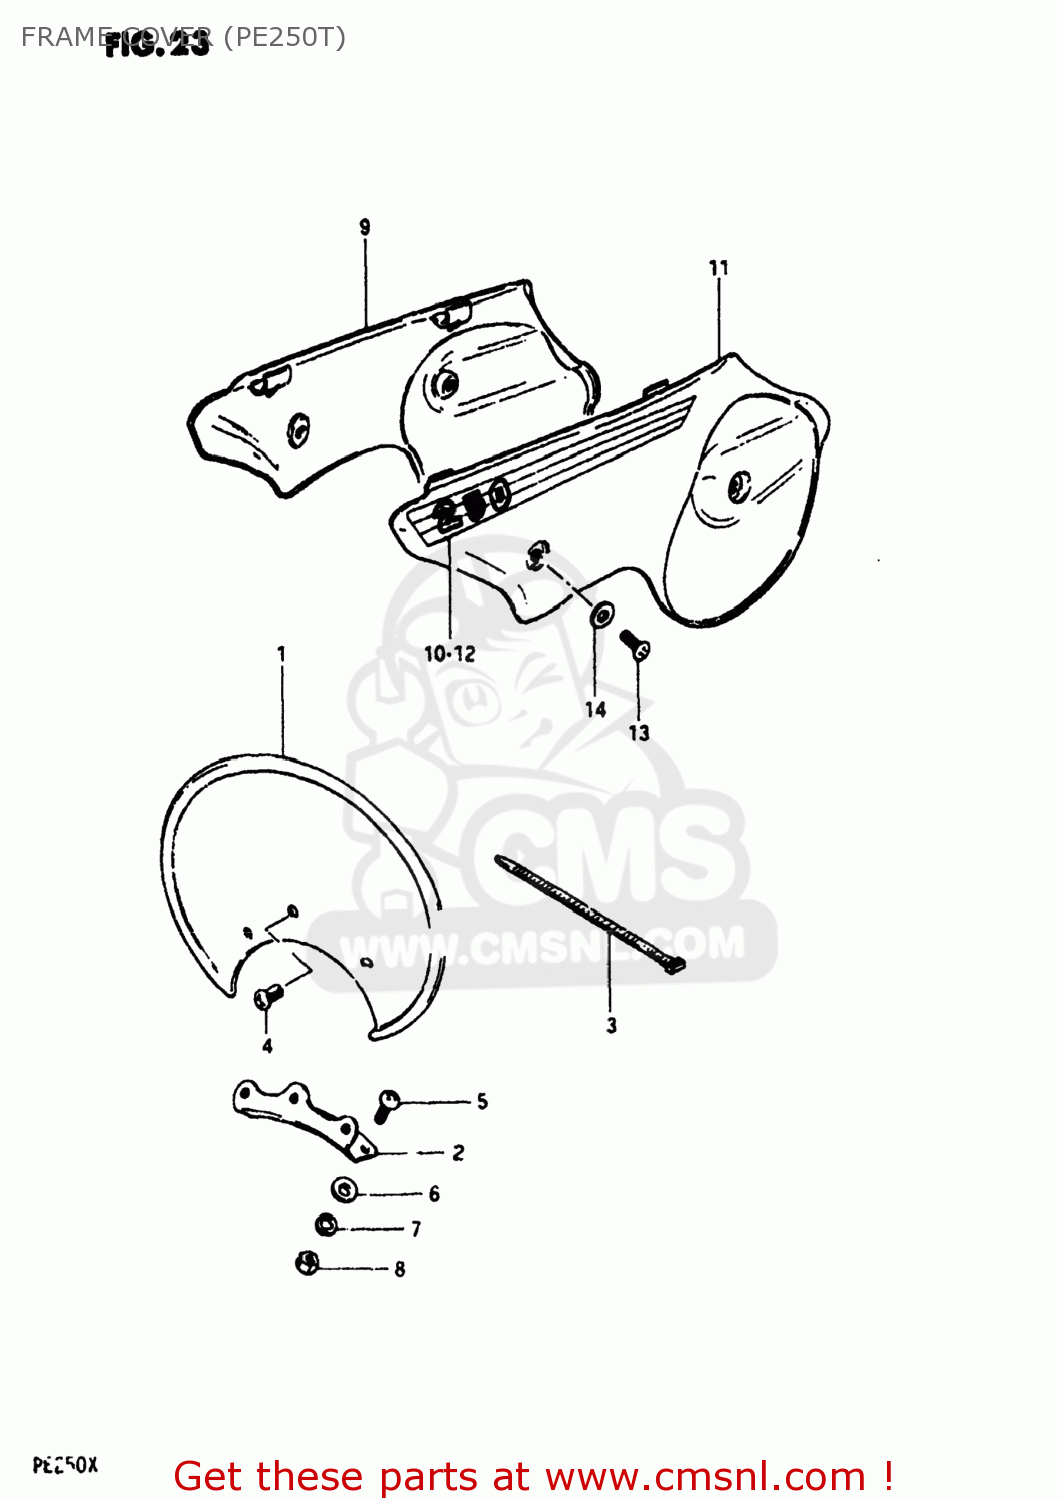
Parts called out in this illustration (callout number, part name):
1	PLATE,NUMBER,FRONT
2	BRACKET
3	CLAMP
4	SCREW
5	SCREW
6	WASHER
7	LOCK WASHER
8	NUT
9	COVER,FRAME,R(YELLOW)
10	TAPE,FRAME COVER,RIGHT
11	COVER,FRAME,L(YELLOW)
12	TAPE,FRAME COVER
13	SCREW 6X12
14	WASHER
